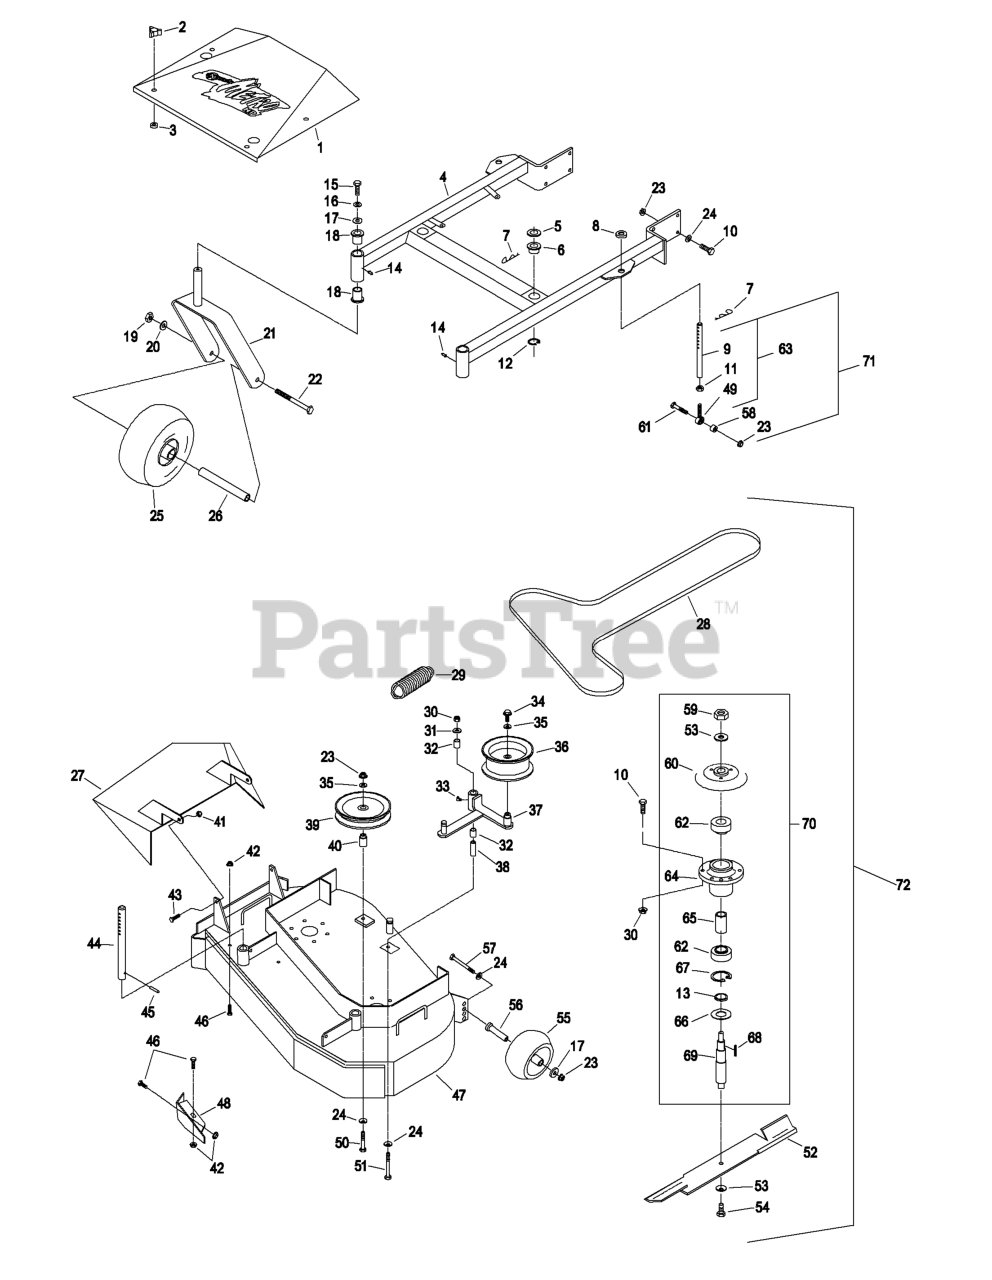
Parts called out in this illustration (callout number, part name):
1	SHIELD W/DECAL,MHP36
2	KNOB-3 PRONG
4	DECK SUPPORT W/BSHGS 36"
5	SPACER-DECK SUPPORT
6	BUSHING-DECK
7	PIN,HAIR COTTER
9	LINK,SUPPORT
10	SCREW-HH
11	NUT-HEX
12	RING-RETAINING
13	SPACER-PULLEY/BEARING
14	FITTING-GREASE
15	SCREW-HH
16	WASHER-LOCK
18	BEARING-FLANGED
19	NUT-HH
20	WASHER-LOCK
22	SCREW-HH
23	NUT-HHF, WHIZ
24	WASHER-BELLEVILLE
28	BELT,DECK DRIVE
30	Nut, Nyloc 3/8-16
31	WASHER-FLAT
32	SLEEVE-BEARING
33	FITTING-GREASE, 90 DEG
34	SCREW-HHF
35	WASHER-FLAT
37	Arm, Weldment
38	BUSHING-PIVOT, IDLER
39	PULLEY-IDLER
40	BUSHING-IDLER
41	NUT-LOCK, NI
43	SCREW-HH
44	ROD,DECK SUPPORT
46	SCREW-HH
47	ASM,DECK W/DECALS TTHP/MH
49	BALLJOINT
50	SCREW-HH
51	SCREW-HH
53	WASHER-SPRING
54	SCREW-CAP
55	ROLLER-SCALP, ANTI
56	BUSHING-ROLLER
57	SCREW-HH
59	NUT-HEX
60	SHEAVE,W/HUB 5.72
61	SCREW-HH
62	BEARING
65	SPACER-BEARING
66	GUARD-BEARING, BOTTOM
67	RING-SNAP
68	KEY-RECTANGLE
69	SHAFT,SPINDLE
70	HOUSING,CUTTER COMPLETE
72	Assembly, Cutting Deck
